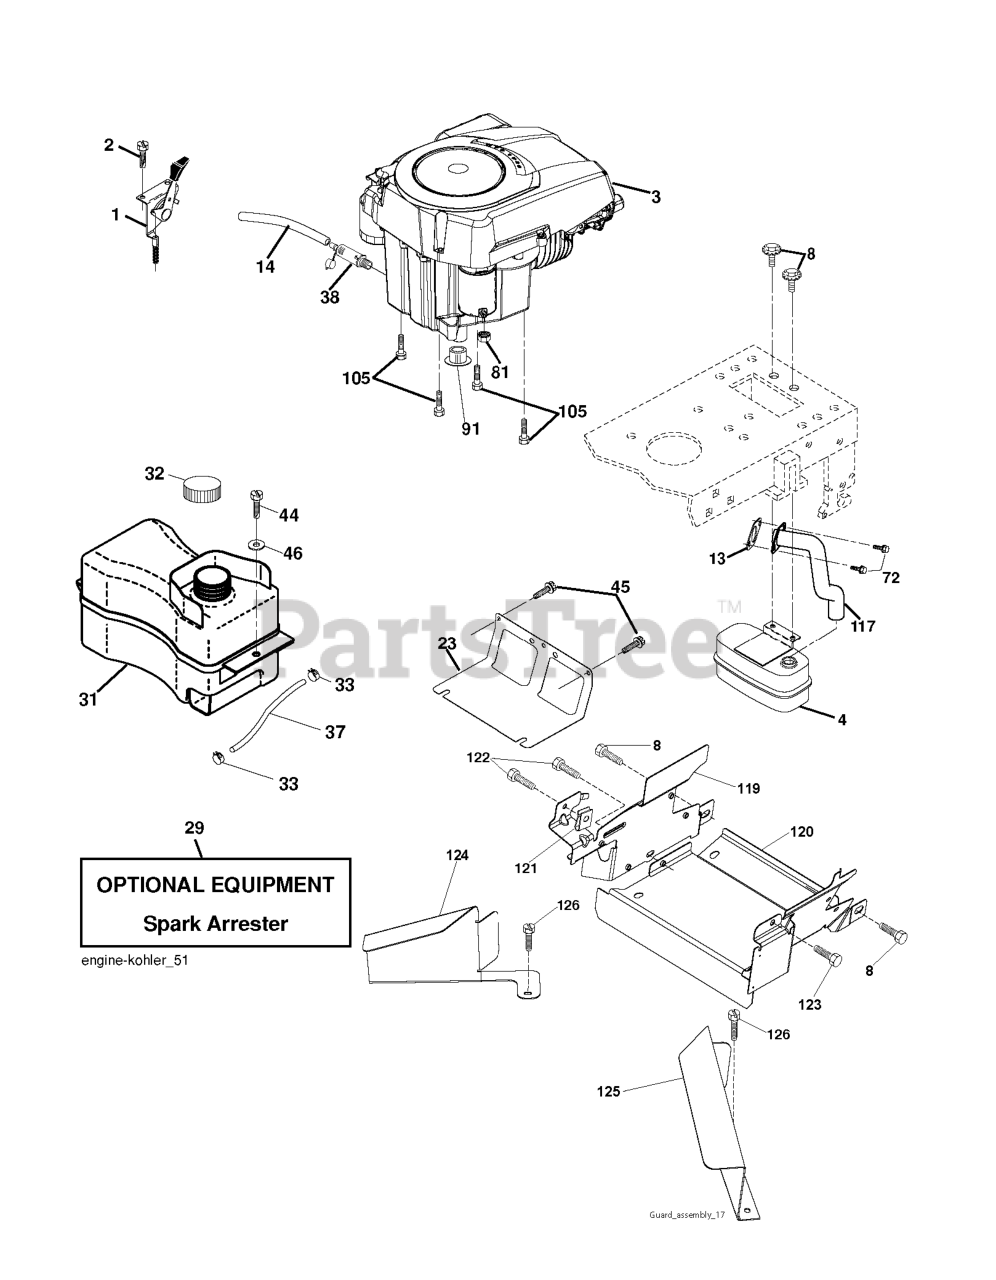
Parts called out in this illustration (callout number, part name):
1	CONTROL.TH/CK.C.
2	SCREW
4	MUFFLER.SINGLE.CYL.KOHL/B&S
8	BOLT.5/16-18UNCX3/4 W/SEMS.BLK
13	GASKET.EXHAUST.KOHLER
14	TUBE, DRAIN OIL ASM.
23	SHIELD.BROWNING.DBR.GUARD
29	KIT.SPARK ARRESTOR 794945 B&S
31	RP TANK FUEL FRT 1.5 GAL
32	FUEL CAP
33	HOSE CLAMP
37	LINE.FUEL.20
38	PLUG DRAIN OIL EASY
44	SCREW HEXWSHR 1/4-20X3/4
45	SCREW, 3/8-16X3/4
72	SCREW.SOCKET HD.5/16-1
81	NUT
91	BUSHING.1.375OD
105	SCREW 3/8-16X1
117	RP.TUBE.EXHAUST.KOHL.COURAGE
119	LENKRAD
120	GUARD 532199767
122	SCREW.1/4-20X5/8
123	SCREW, 5/16-18 X 1/2
126	SCREW
